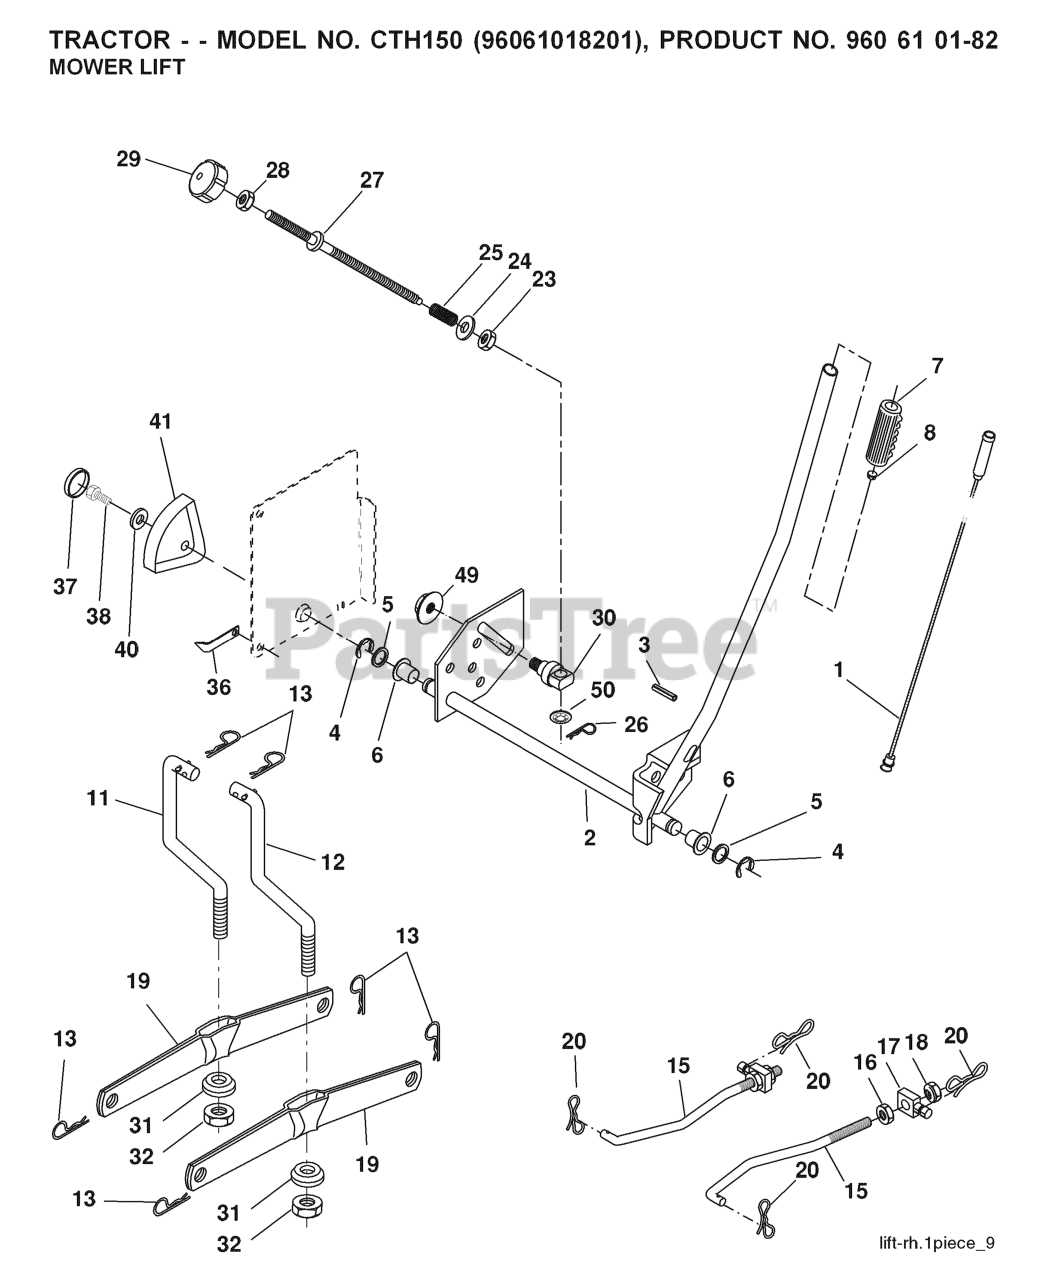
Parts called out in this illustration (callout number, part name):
2	SHAFT.ASM.LIFT.YT
3	PIN.GROOVE.5/16
4	RETAINING RING LT
6	BEARING.NYLON
7	GRIP HANDLE
8	REPL BY 532 12 59-25
11	LINK
12	LINK
13	RETAINER-SPRNG RB
15	LINK.SUSPENSION.FRONT
16	NUT.HEX.JAM.1/2-13
18	NUT.LK.W/WSH.1/2.
19	ARM.REAR.SUSPENSION
20	PIN.COTTER.7/16.BOW TI.
26	RETAINER CLIP
27	ROD ADJ LIFT
28	NUT
29	KNOB INF 3/8-16
31	BEARING.PIVOT.LIFT
32	NUT CROWNLOCK 3/8-24
36	POINTER, HEIGHT INDICATOR(2 2)
38	SCREW 5/16-18X1
41	HEIGHT INDICATOR
49	NUT
50	NUT PUSH M
